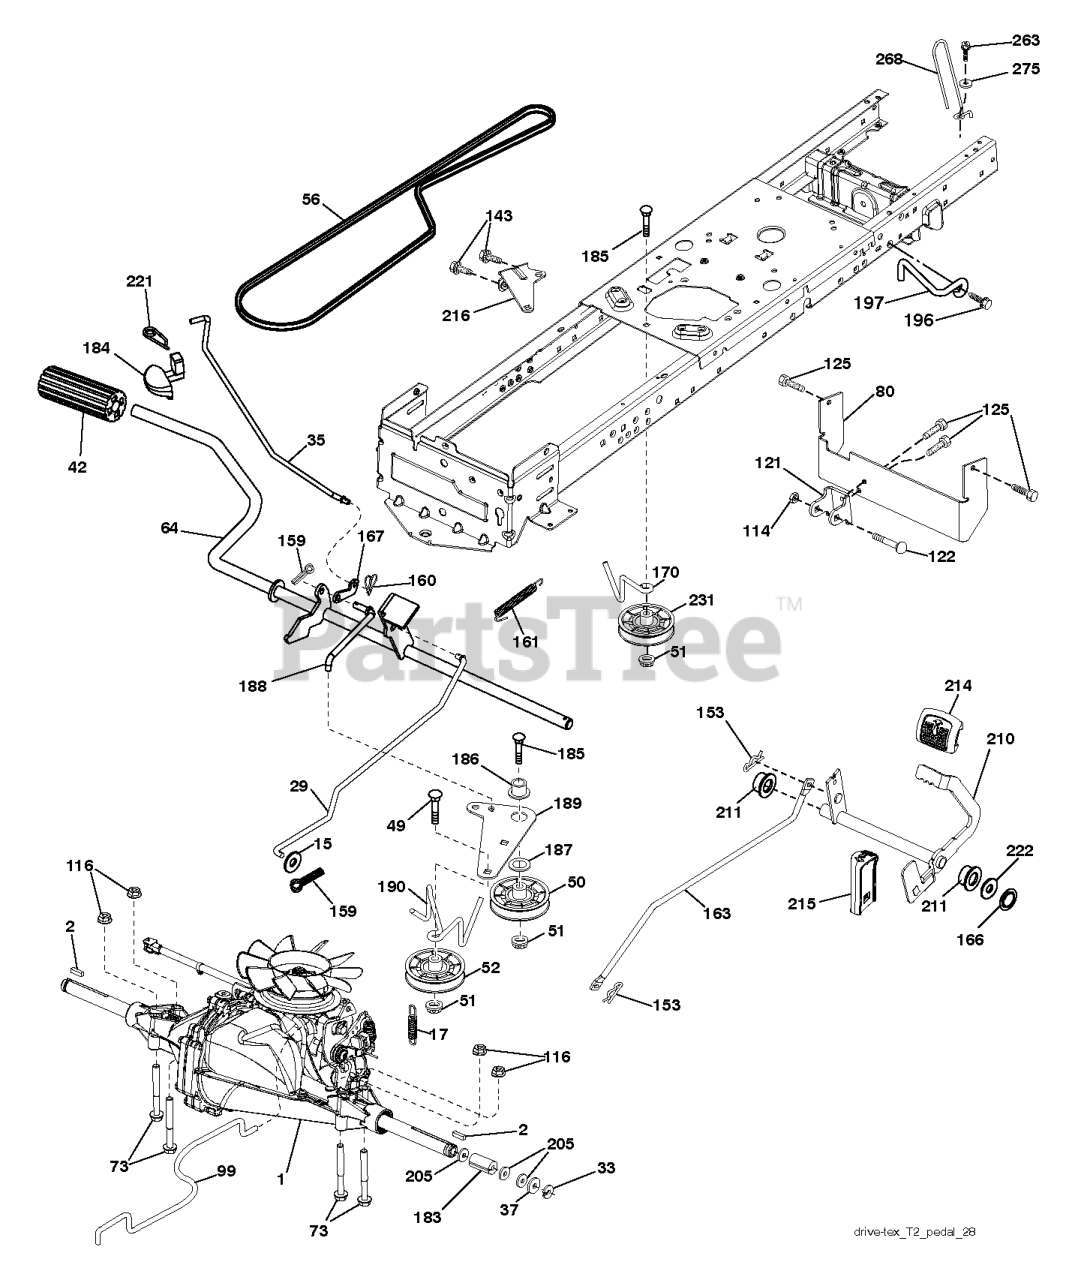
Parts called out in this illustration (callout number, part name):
1	Husqvarna TBD
2	SQUARE KEY
15	WASHER
17	SPRING.BRAKE.HG3000/3500
29	ROD.BRAKE.T2.TEX
35	ROD.CNTRL.PARK.PREDATOR.LT.TEX
42	PEDAL COVER T
50	IDLER.FLAT.910.OFFSET
51	NUT LOCK FLG 3/8-16 UNC
52	IDLER.V-GROOVE.910.OFFSET
64	SHAFT.ASM.PEDAL.BRK.CNTR
73	BOLT HEX 5/16-18 GR 5
80	RP.STRAP.TORQUE.FS.T2
99	ROD.ASM.BYPASS.SPRING.T2.FS
114	NUT.71038.31-18.HEX.NYLOCK
116	NUT LOCK HEX FLANGE 5/16-18
121	BRACKET STRAP TORQUE
122	BOLT.5/16-18X2.5
125	SCREW
143	SCREW LT
153	RETAINER M
159	COTTER PIN
160	RETAINER CLIP
161	SPRING, RETURN LT
163	ROD.CONTROL.PCH.T2.TEX
166	NUT.PUSH.625
167	LATCH.BRAKE.SPRING
170	KEEPER.CENTER SPAN.1.688
183	SPACER, AXLE PVST
184	HANDLE PARKING BRAKE
186	SPACER.RETAINER
187	WASHER 12/32X2X10GA
188	RP.LINK.CLUTCH.GROUND.DRIVE
189	BELLCRANK.GROUND.DRIVE.TEX.
190	KEEPER.BELLCRANK.DRIVE
196	SCREW 3/8-16X1
197	LINK.CLUTCH.ANIT-ROTAT
210	ROCKER.ASM.PEDAL.CONTR
211	BEARING.NYLON
214	PEDAL.FORWARD.PAD.TEX
215	PEDAL RUBBER REVERSE
216	BRACKET.PULLEY.IDLER.W/TEX
221	RETAINER.SPRING.CLIP.H
222	WASHER 21/32 X 1-1/4 X 10 GA.
231	IDLER.V-GROOVE.1.688.OFFSET
263	SCREW, 3/8-16X3/4
268	GUARD MUFFLER
275	WASHER
